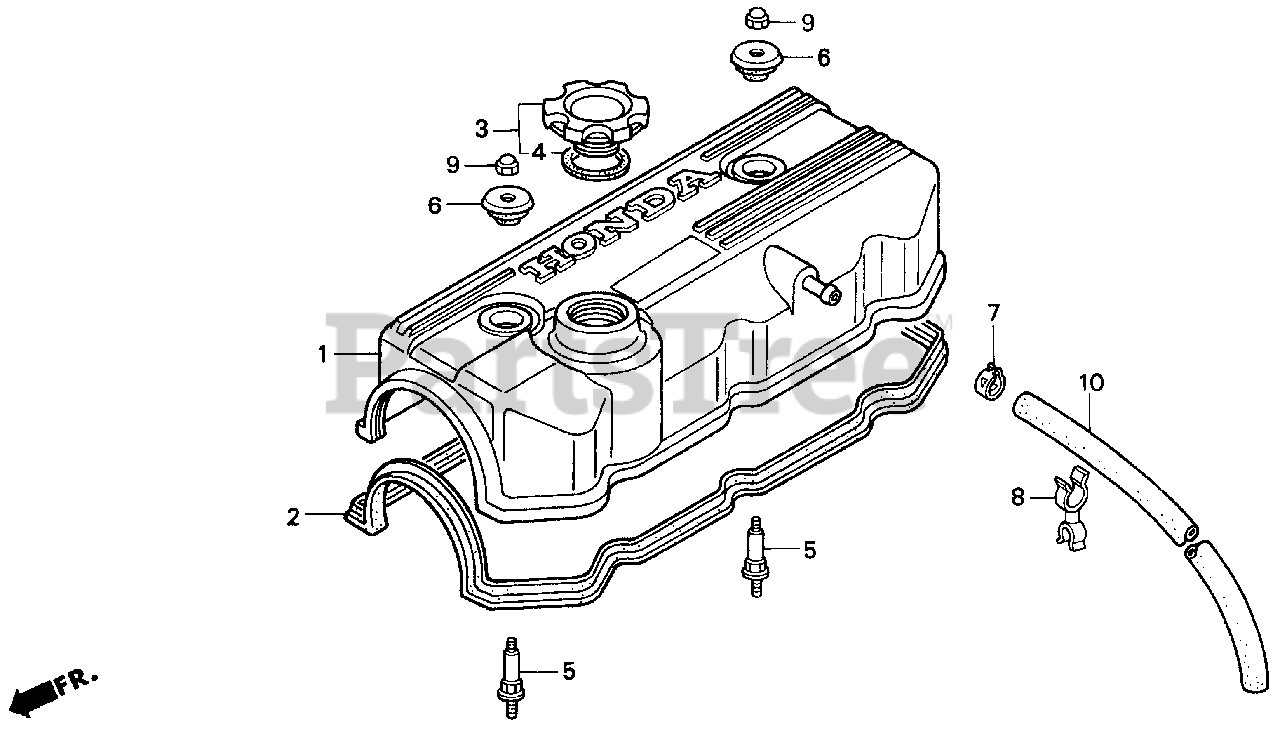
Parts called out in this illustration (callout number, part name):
1	COVER, HEAD
2	GASKET, HEAD COVER
3	CAP ASSY., OIL FILLER
4	GASKET, OIL FILLER
5	BOLT, HEAD COVER
6	WASHER, HEAD COVER
7	CLAMP, CANISTER HOSE
8	CLAMP, PIPE (B)
9	NUT, CAP (6MM)
10	BULK HOSE, VACUUM (11X1000) (11X570)
